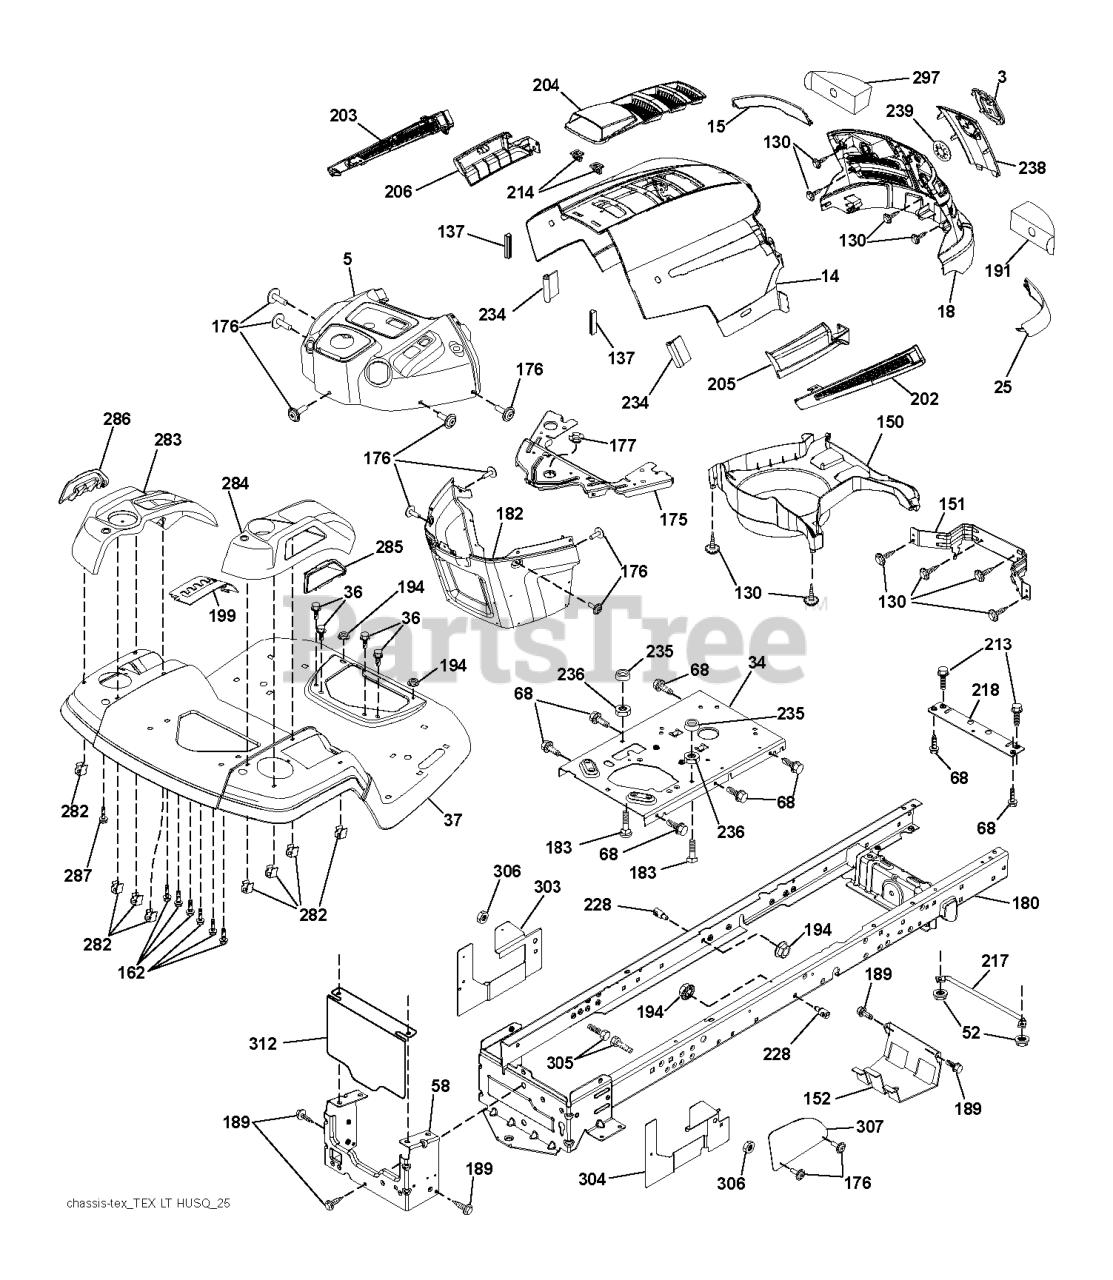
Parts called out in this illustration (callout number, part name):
3	RP LOGO
5	DASH
14	HOOD
15	LENS.HUSQVARNA LT.LH
18	RP GRILLE/LENS ASM.
25	LENS.HUSQVARNA LT.RH
34	PLATE.ENGINE.WELDED.CHASSIS
36	SCREW 5/16"
37	RP FENDER.TLT.FS.W/CPH.422
52	LOCKNUT
58	DRAWBAR UPPER 2PC SMALL FENDER
68	Screw 5/16-18 x 1/2 Hex, Self Tapping 5/16-18 x 1/2
130	SCREW.#10 X 0.750.BOS
137	BUMPER DASH
151	BRACKET PIVOT
152	SHIELD.BROWNING.W/TEX
162	SCREW.HI-LO.CONSOLE
175	CROSSMEMBER
176	SCREW.#10-24X5/8.RN.QU
177	BUSHING STEERING
180	CHASSIS.WLDMNT.14GA.2PC.18".TI
182	DASH.LOWER.PREDATOR LT
183	BOLT.5/16-18X1-1/4 FULL.THREAD
189	SCREW
191	INSERT.REFLECTIVE.RH.
194	NUT LOCK HEX FLANGE 5/16-18
199	PLATE.DECK.LIFT.HUSQ.LT
202	VENT SIDE HOOD LH
203	VENT SIDE HOOD RH
204	VENT TOP HOOD
205	SKIRT SIDE RH
206	SKIRT SIDE LH
213	BOLT
214	CLIP.RETAINER.TINNER.
217	ROD.PIVOT.HOOD
218	X-PIECE.HOOD.STOP.NON/
228	STUD.FASTNER.W/ANTI-ROTATE
234	BUMPER.HOOD.TEX.HUSQVARNA
235	SPACER FENDER
236	NUT.CENTERLOCK.5/16-
238	TRIM
282	CLIP.RETAINER.CONSOLE.LT.HUSQ
283	CONSOLE.DECK.LIFT.HUSQ.N/FR.GR
284	CONSOLE.CNTRL.
285	CONSOLE INSERT RH
286	CONSOLE.INSRT.LH.HUSQ.LT.BLACK
287	SCREW 1/4X20
288	WASHER
297	INSERT REFLECTIVE
303	SHIELD CHASSIS LEFT
306	NUT LOCK FLG 3/8-16 UNC
307	SHIELD UPPER PEDAL
